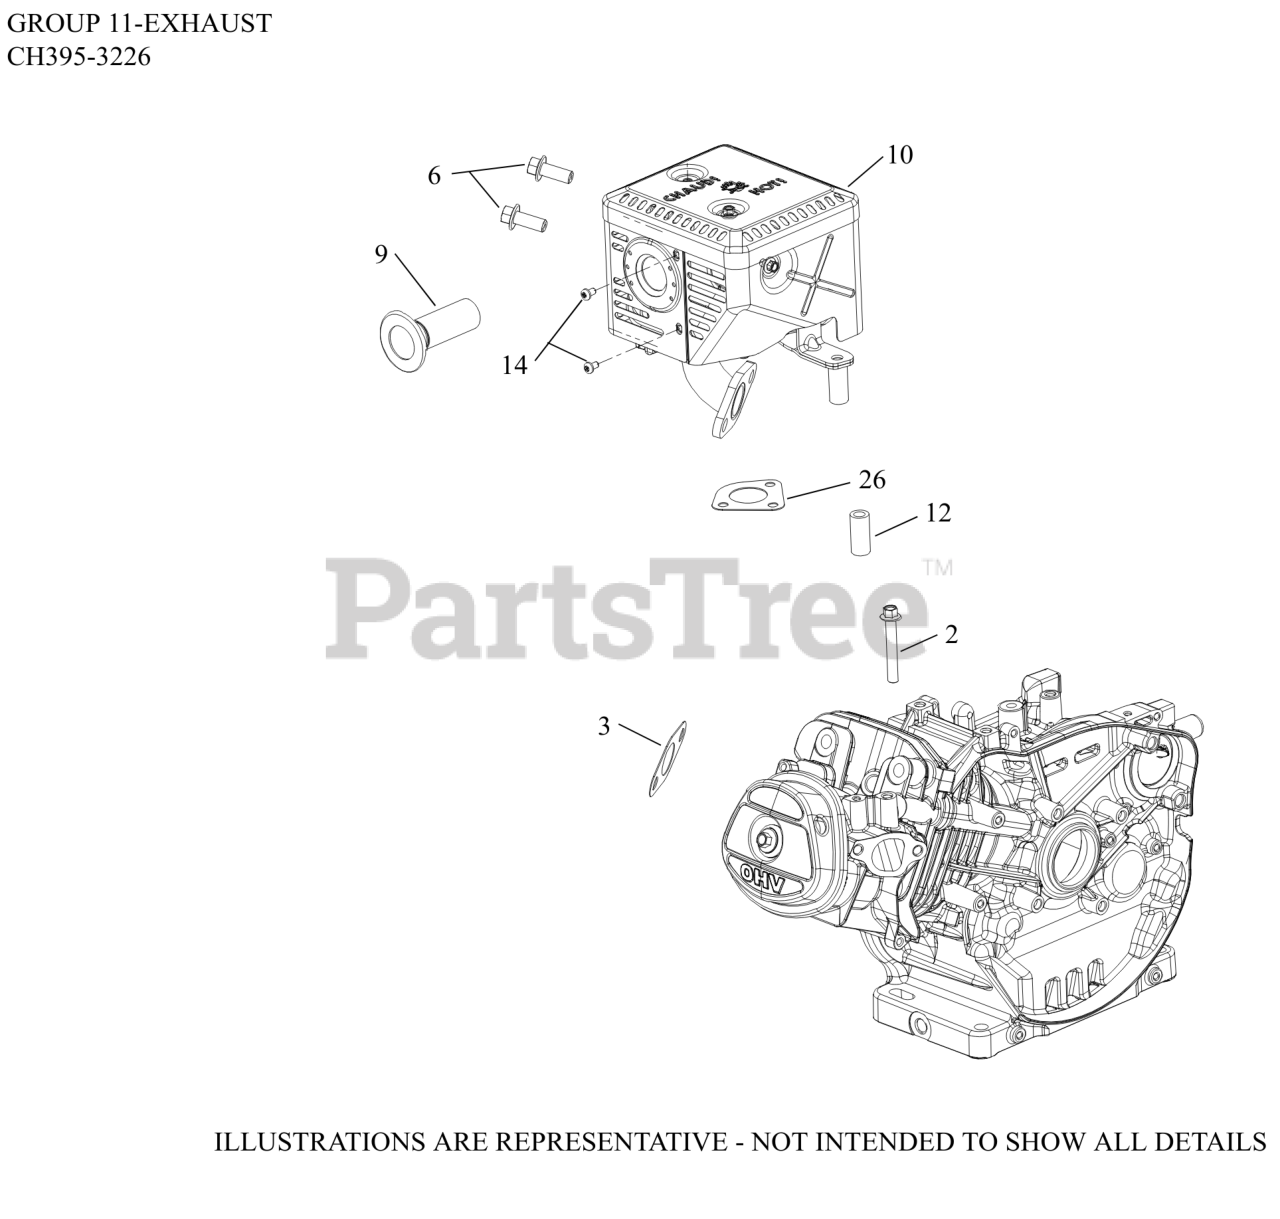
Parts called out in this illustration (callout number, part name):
2	SCREW, M8 X 55
3	GASKET, MUFFLER
6	SCREW, M10 X 25
9	ARRESTOR ASSEMBLY, SPARK
10	MUFFLER ASSEMBLY W/HEAT SHIELD
12	POST, MUFFLER BRACKET
14	SCREW, M5 X 8
26	GASKET, MUFFLER
